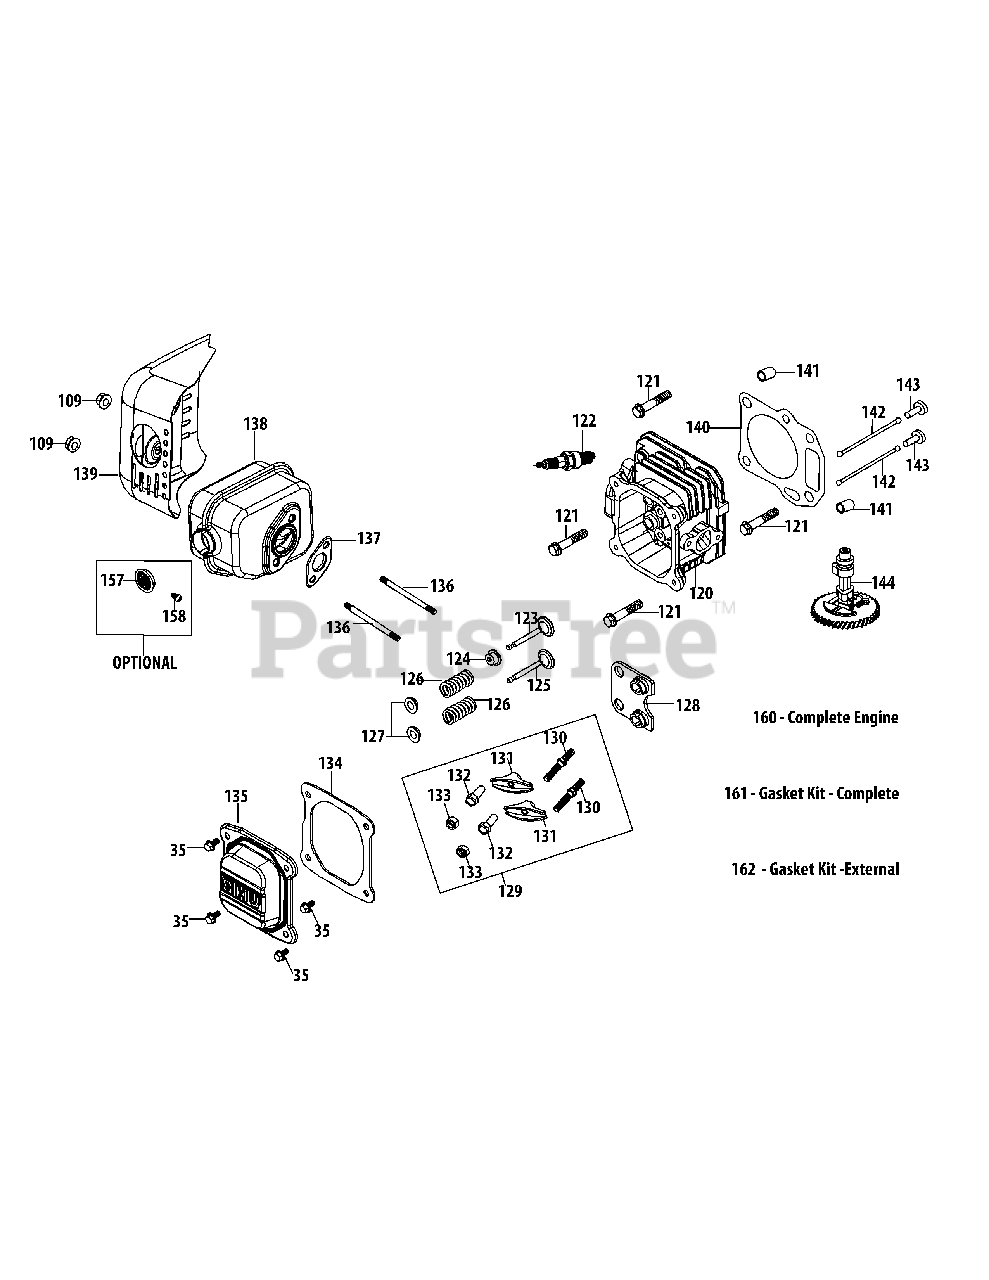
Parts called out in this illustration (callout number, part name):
35	Bolt M6X14 Multi-Purpose
109	Nut M6X10Mm Starter/Carb/Muff
120	Cylinder Head Asm
120	Cylinder Head Service Kit
121	Bolt M8X54 Cylinder Head
122	Spark Plug/F5Rtc
124	Intake Valve Seal
126	Valve Spring
127	Valve Spring Retainer
128	Push Rod Guide
129	Rocker Arm Assembly
130	Rocker Arm Stud
131	Rocker Arm
132	Fulcrum Nut
134	Valve Cover Gasket
135	Valve Cover
136	Muffler Stud Assy
137	Muffler Gasket
138	Muffler Assembly
139	Muffler Shield
140	Cylinder Head Gasket
141	Cylinder Head Dowel Pin 10×16
142	Push Rod Kit
143	Tappet
144	Camshaft Assembly
157	Spark Arrestor
158	Spark Arrestor Screw
160	Complete Engine
161	Gasket Kit - Complete
162	Gasket Kit -External
